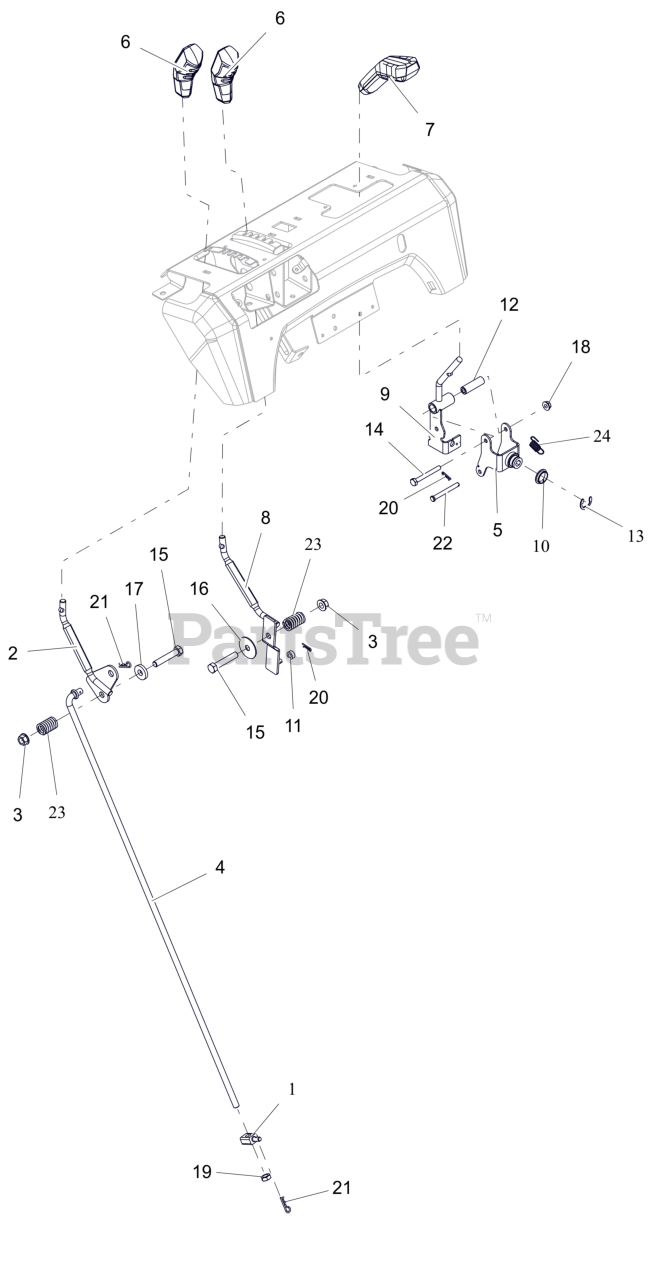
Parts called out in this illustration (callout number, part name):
1	PIVOT,SHIFT ROD .375-16(TRUNN)
2	WELDMENT,LG DASH SPEED CONTROL
3	NUT-LK-TOP-FLG .38-16 ZC120
4	ROD, SHIFT - LARGE DASH DELUXE
5	WELDMENT, CONTROL BRACKET
6	KNOB, CONTROL
7	HANDLE, QUICK TURN
8	WELDMENT,LG DASH DEFL CONTROL
9	WELDMENT, CONTROL LEVER
10	BUSHING, POLYLINER-.75 SNAPIN
11	BSHG-SLV .265X.500X.219
12	BSHG, SLV .265X.505X1.665
13	E-RING .750X.050
14	BLT,HEX .25-20X2.25 G5 ZCC
15	BLT,HEX .38-16X2.00 G5 ZCC
16	WSHR,FLT .380X1.50X.062 ZCC
17	WSHR, FLT .406X1.00X.188 ZCC
18	NUT-LK-CTR-FLG .25-20 ZC120
19	NUT-JAM .375-16 G2 ZCC
20	PIN, HAIR #178 .06X.77 ZCC
21	PIN, HAIR #213 .08X1.19 ZCC
22	PIN, CLEVIS - .25 X 2.25 ZCC
23	SG-COMP .125X.781X1.250
24	SPRING-EXT .047X.438X1.45
